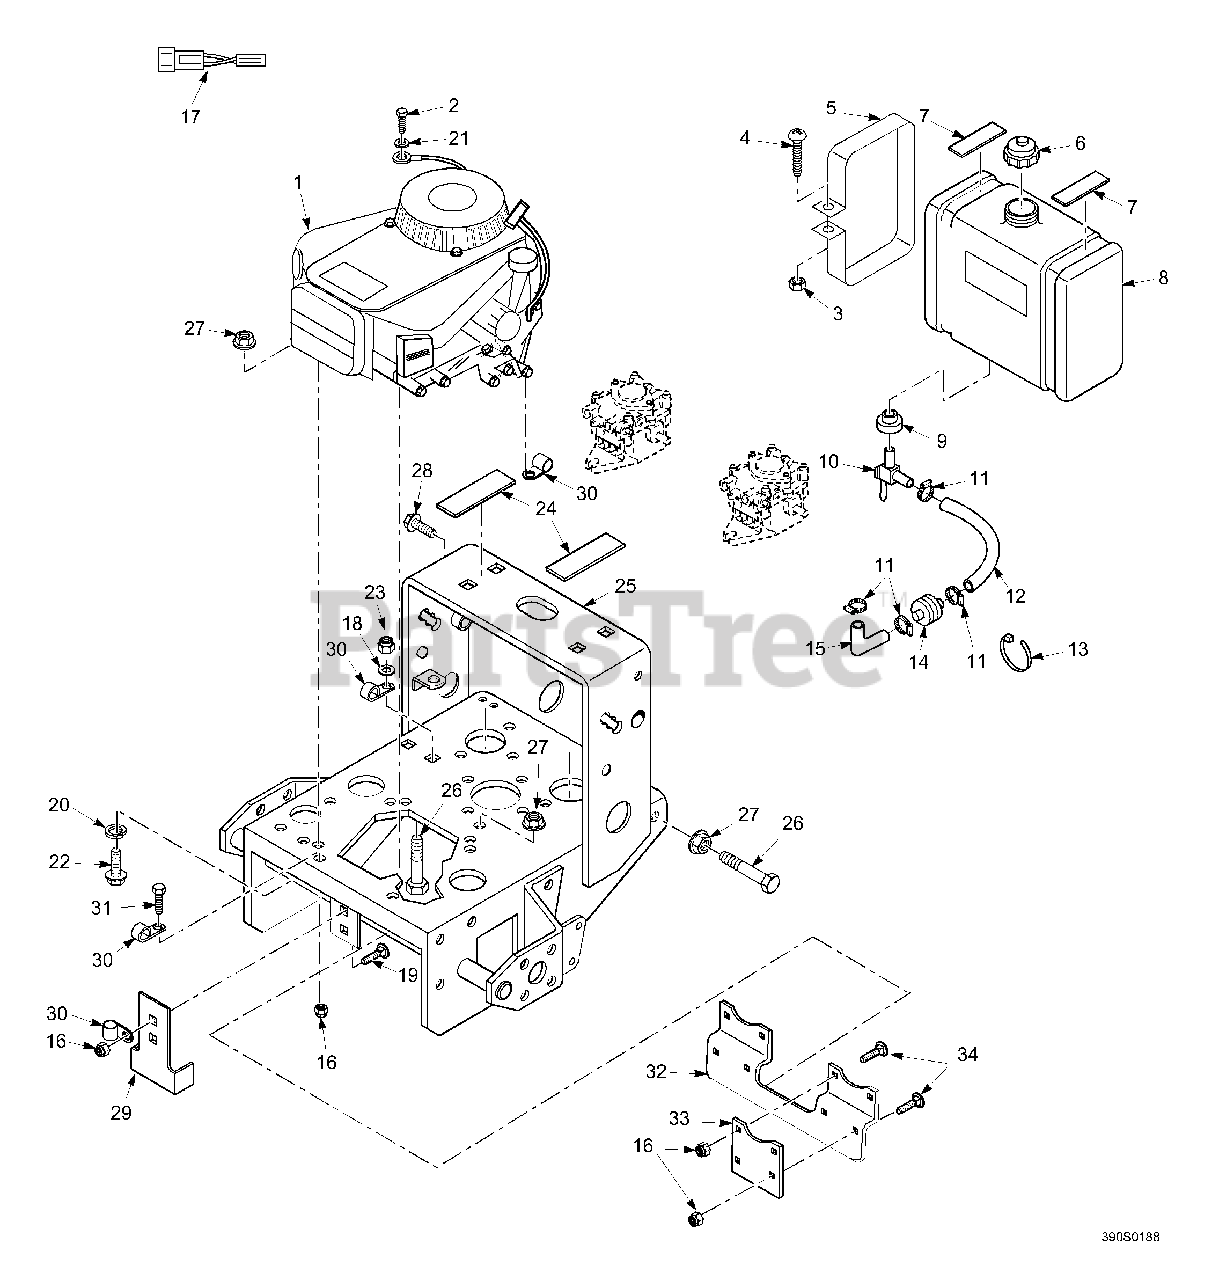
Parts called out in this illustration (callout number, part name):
1	Engine,21KAE Kawasaki
2	Bolt, Hex Head M8-1.25 x 10mm
3	Hex Nut, 1/4-20
4	Screw, 1/4-20 x 2" Round Head Phillips
5	Strap, Fuel Tank
6	Cap, Fuel Tank
7	Pad, Rubber-Fuel Tank Upper
8	Fuel Tank Assembly
9	Bushing
10	Valve, Fuel Shut-Off
11	Clamp, Fuel Hose
12	Fuel Hose, 1/4 I.D. x 20"
13	Cable Tie, .19 x 8.0"
14	Fuel Filter
15	Fuel Hose, 7/32 I.D. x 3.5"
16	Nut, Hex Elastic Stop 5/16-18
17	Wire Harness Adapter
18	Flat Washer, 14"
19	Bolt, Carriage 5/16-18 x 1"
20	Lock Washer, 5/16"
21	Lock Washer, 5/16" Int. Tooth
22	Bolt, Hex Head M8-1.25 x 30mm
23	Nut, Hex Elastic Stop 1/4-20
24	Pad, Rubber-Fuel Tank Lower
25	Engine Deck, 20" Wide W/Decals
26	Bolt, Hex Head 1/4-20 x 1.25"
27	Nut, Hex Serrated Flange 1/4-20
28	Capscrew, Hex Serrated Flange 5/16-18 x 1.25"
30	Clutch Bracket
31	Bolt, Hex Head 5/16-18 x .75"
32	Stiffener (large frame units only)
33	Plate (large frame units only)
34	Bolt, Carriage 5/16-18x1" (large frame units only)
